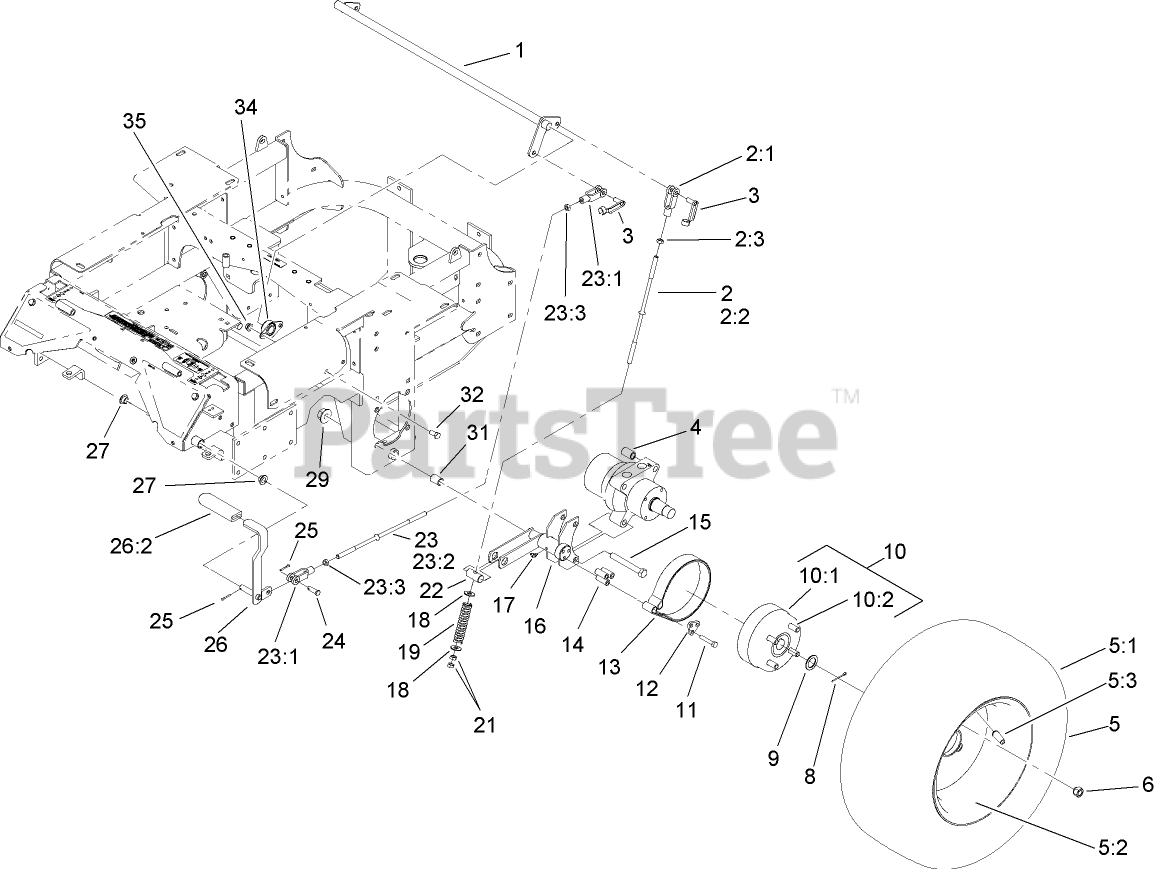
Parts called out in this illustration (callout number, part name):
1	SHAFT-BRAKE
2	BRAKE ROD ASM
2:1	YOKE-LINKAGE, BRAKE
2:2	ROD-BRAKE
2:3	NUT-HEX
3	Pin-Spring, Clevis
4	SPACER-WHEEL, LONG
5	WHEEL AND TIRE ASM
5:2	WHEEL RIM
5:3	STEM-VALVE
6	NUT-LUG
8	PIN-COTTER
9	WASHER-SPACER
10	WHEEL HUB ASM
10:1	HUB-WHEEL
10:2	STUD-WHEEL
11	SCREW-HH
12	RETAINER-BAND, BRAKE
13	BAND-BRAKE
14	SPACER
15	SCREW-HH
16	BRACKET-BRAKE
17	FITTING-GREASE
18	WASHER-FLAT
19	SPRING-BRAKE
21	NUT-HEX
22	PIN-TRUNION
23	BRAKE ROD ASM
23:1	YOKE-LINKAGE, BRAKE
23:2	ROD-BRAKE
23:3	NUT-HEX
24	PIN-CLEVIS
25	PIN-COTTER
26	BRAKE LEVER ASM
26:2	GRIP-LEVER
27	BEARING-CONTROL
29	NUT-HHF
31	SPACER-WHEEL, SHORT
32	SCREW-HH
34	BEARING-FLANGE, SIDE
35	NUT-HHF, WHIZ
